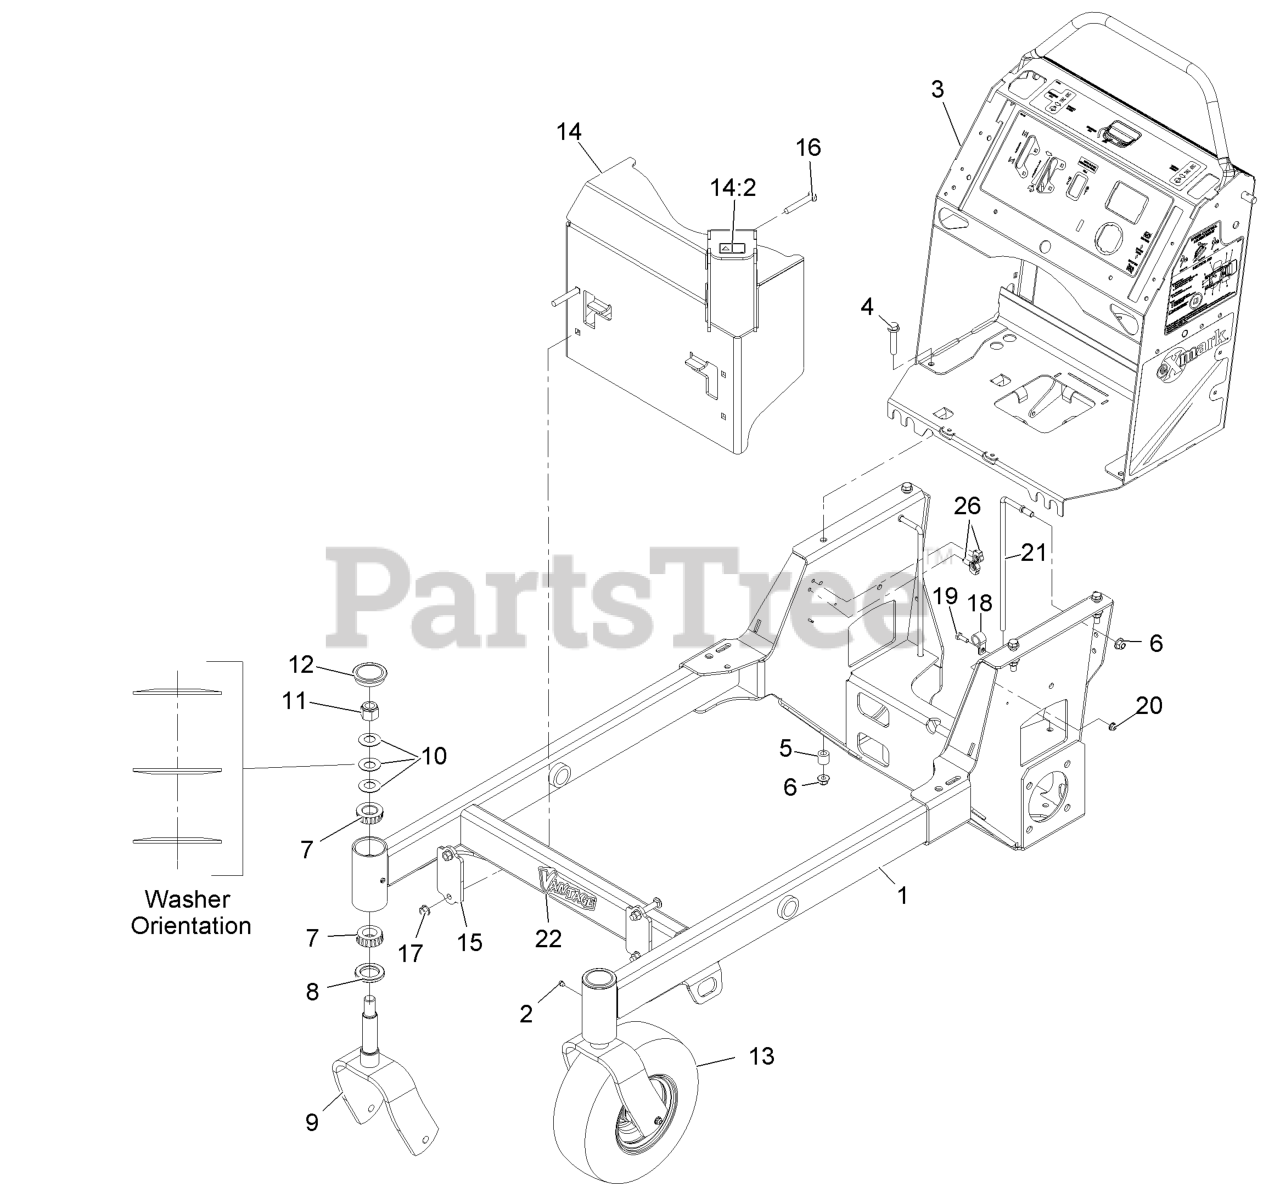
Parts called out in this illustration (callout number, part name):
1	FRAME ASM
3	CONTROL TOWER ASM
4	SCREW-HHF
6	NUT-HF, NI
7	Cone-Bearing Tapered Roller
8	SEAL-GREASE
9	FORK-CASTER
10	WASHER-BELLVILLE
11	NUT-LOCK, NI
12	CAP-GREASE
13	WHEEL/TIRE AND BEARING AS
14:2	DECAL-WARNING
15	BRACKET-MOUNTING, GUARD
16	SCREW-CARR
18	CLAMP-CABLE
19	SCREW-HH
21	GUIDE-HOSE
22	DECAL-VANTAGE LOGO
26	CLIP-HARNESS
